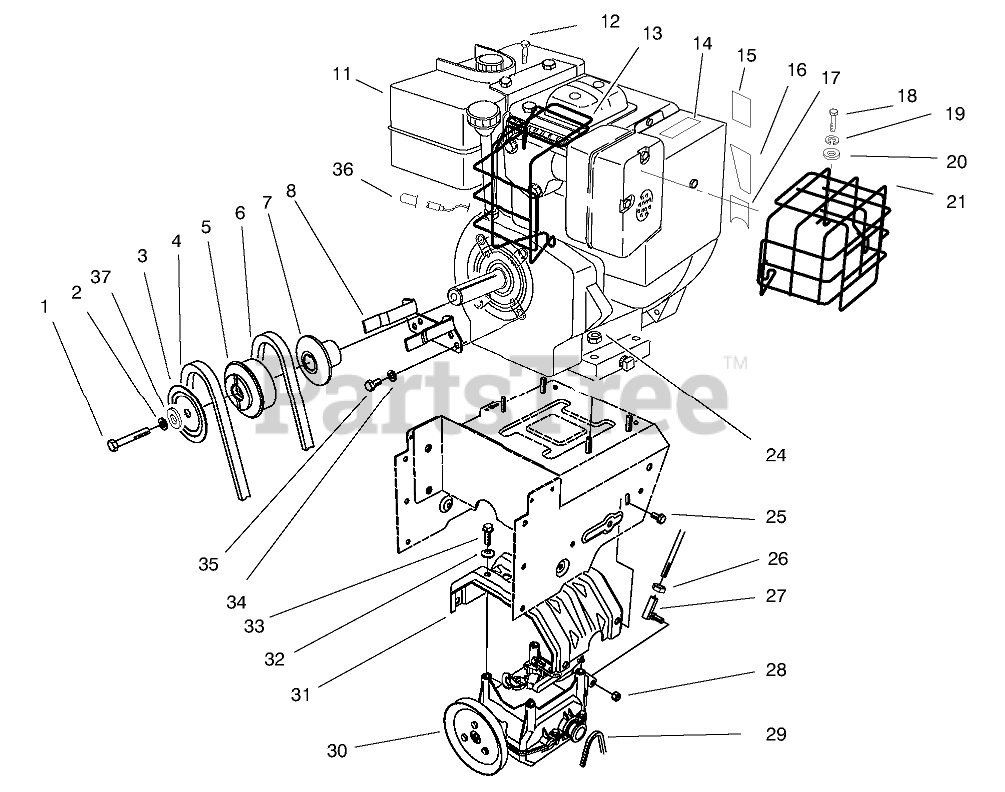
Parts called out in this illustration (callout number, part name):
1	SCREW-HH
2	WASHER-LOCK
3	SHEAVE-HALF, IMPELLER
4	V-BELT
5	PULLEY-ENGINE, CENTER
6	V-BELT, TRACTION
7	SHEAVE-HALF, TRACTION
8	Guide-Belt
12	Screw / Washer, Model 38591
13	Guard-Muffler, Model 38591
14	DECAL-WARNING, HOT SURFACE
15	DECAL - PRIMER
16	THROTTLE DECAL, INT'L
17	DECAL-CHOKE
18	Screw
19	Washer-Lock
20	Washer-Flat
21	Guard-Muffler, Model 38591
24	NUT-HF
25	SCREW-HHF
26	NUT-HJ
27	BALL-JOINT
28	NUT-LOCK
29	CHAIN
30	TRACTION GEARCASE ASM
31	Frame-Transmission
32	WASHER-SPRING
33	SCREW-HWHTF
34	WASHER-LOCK
35	SCREW-HH
36	CAP-WIRE, LITE
37	WASHER
